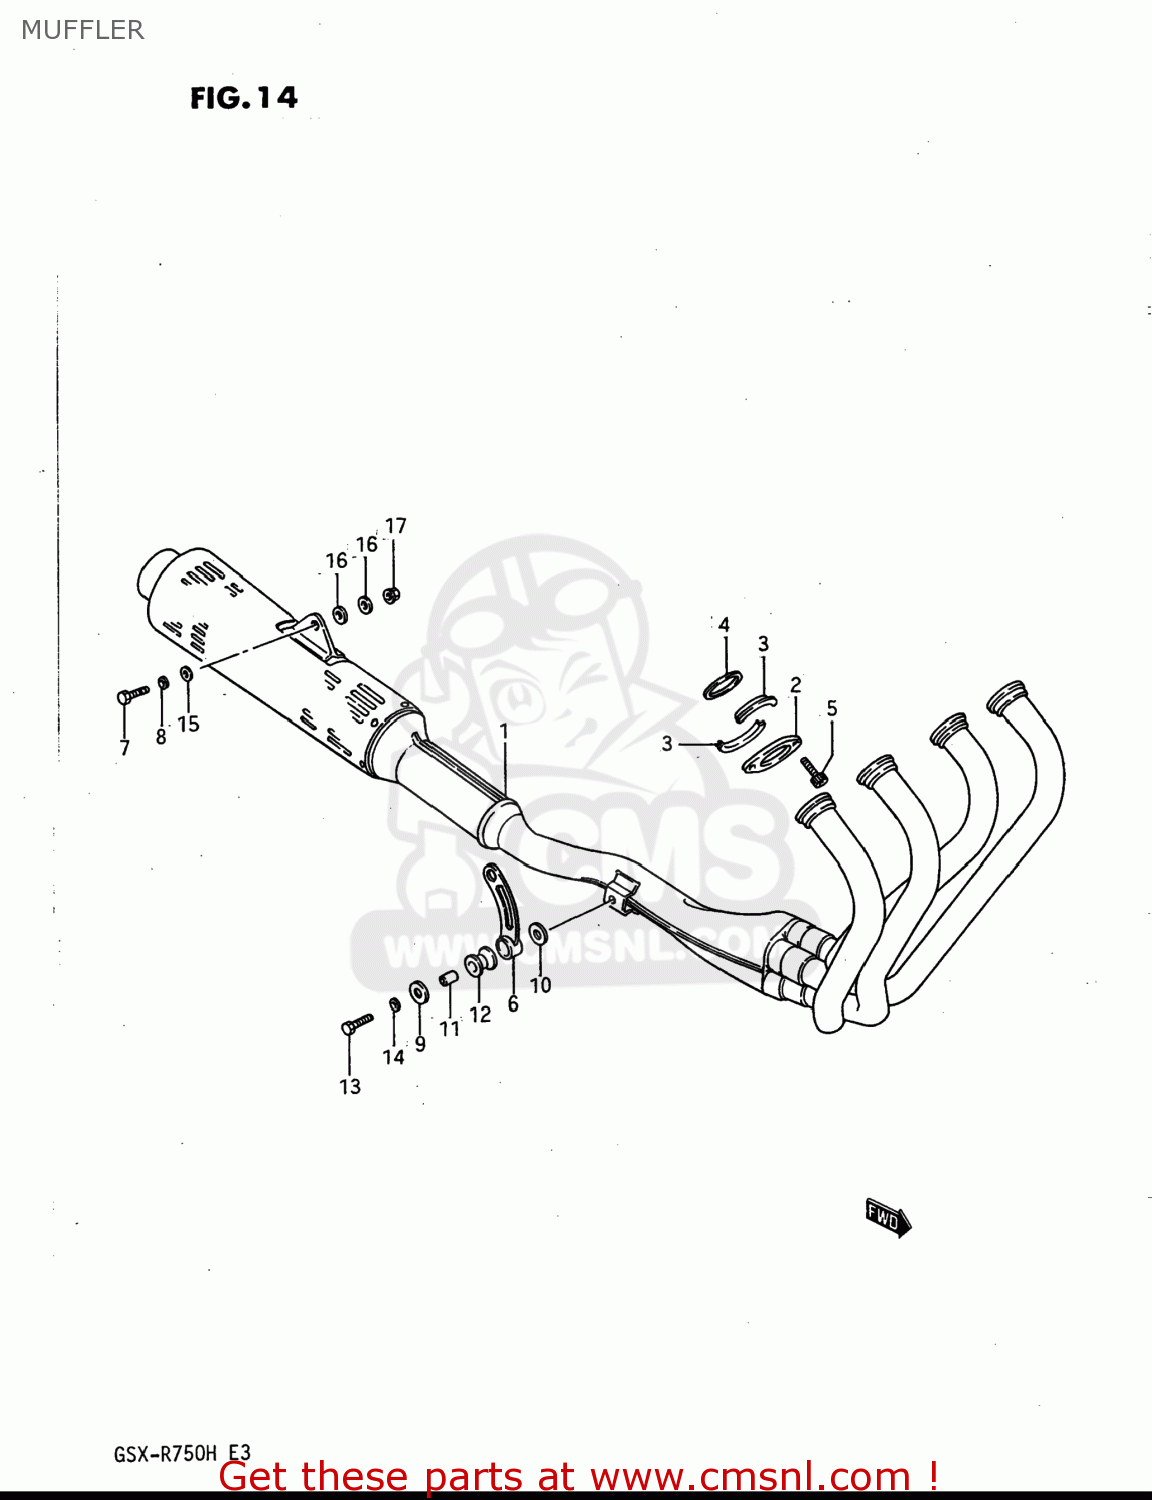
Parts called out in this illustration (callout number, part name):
1	MUFFLER ASSEMBLY
2	CLAMP,EXHAUST PIPE
3	PLATE,EXHAUST PIPE
4	GASKET,EXHAUST PIPE (NAS)
5	BOLT
6	DAMPER,MUFFLER SUPPORT
7	BOLT 8X35
8	WASHER
9	WASHER
10	WASHER (8.5X20X1.6)
11	SPACER (8.6X12X17.5)
12	CUSHION
13	BOLT
14	WASHER,LOCK
15	WASHER 10MM
16	WASHER
17	NUT
